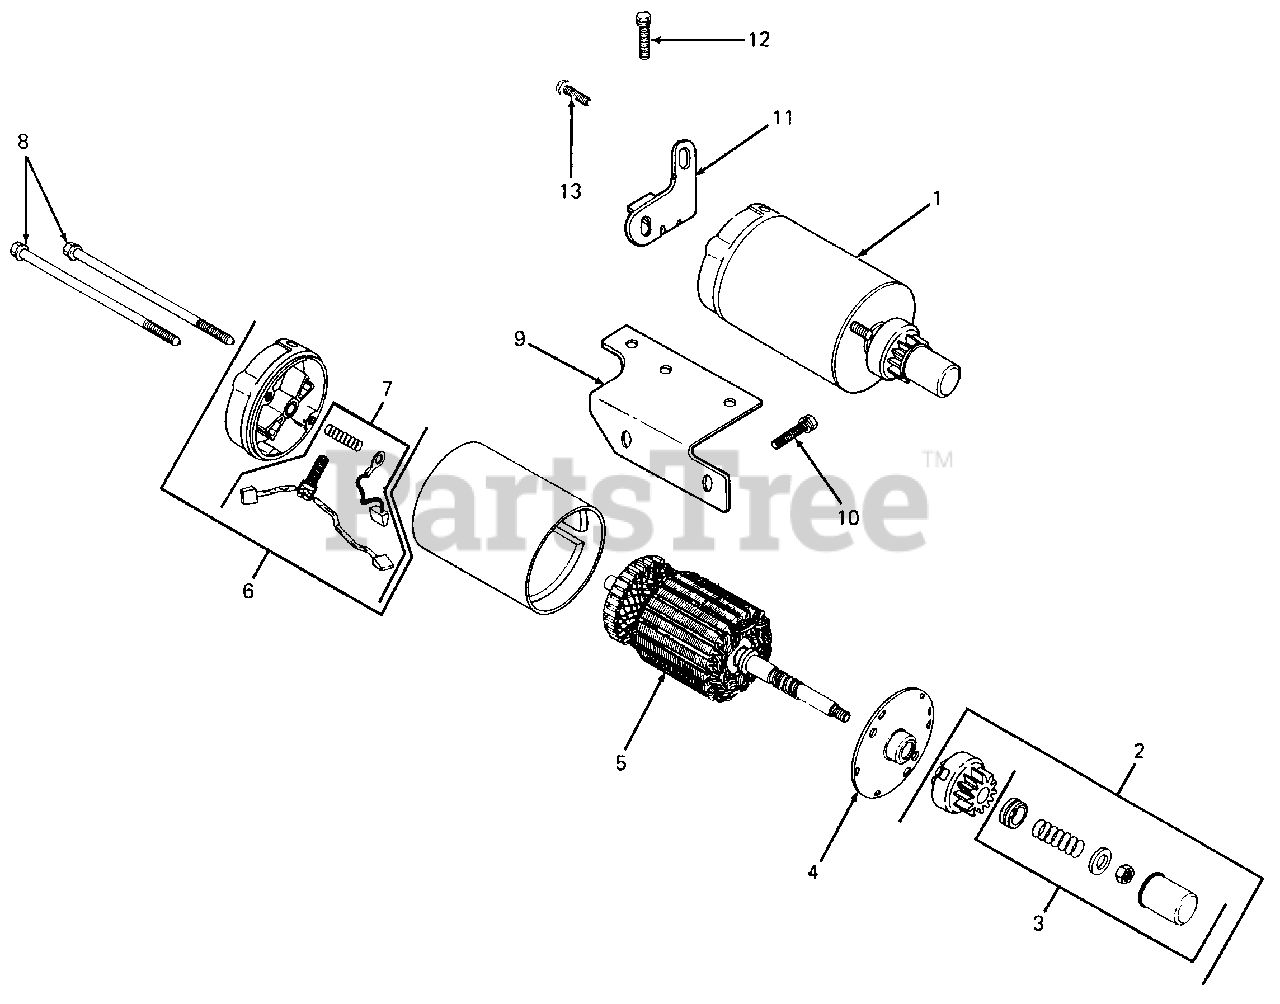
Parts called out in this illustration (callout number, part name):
1	Starter Assembly
2	Kit, Drive
3	Kit, Drive Parts
4	Cap, Drive End
6	Cap, Commutator End
7	Kit, Brush
8	Bolt, 1/4-20 X 5-1/16 Lg
9	Bracket, Solenoid
10	Screw, HC Sems, 3/8-16 X 1.0 Lg
12	Screw, Hex Wash Hd, 1/4-20 X .75 Lg
13	Screw, Hex Wash Hd, 1/4-20 X .38 Lg
